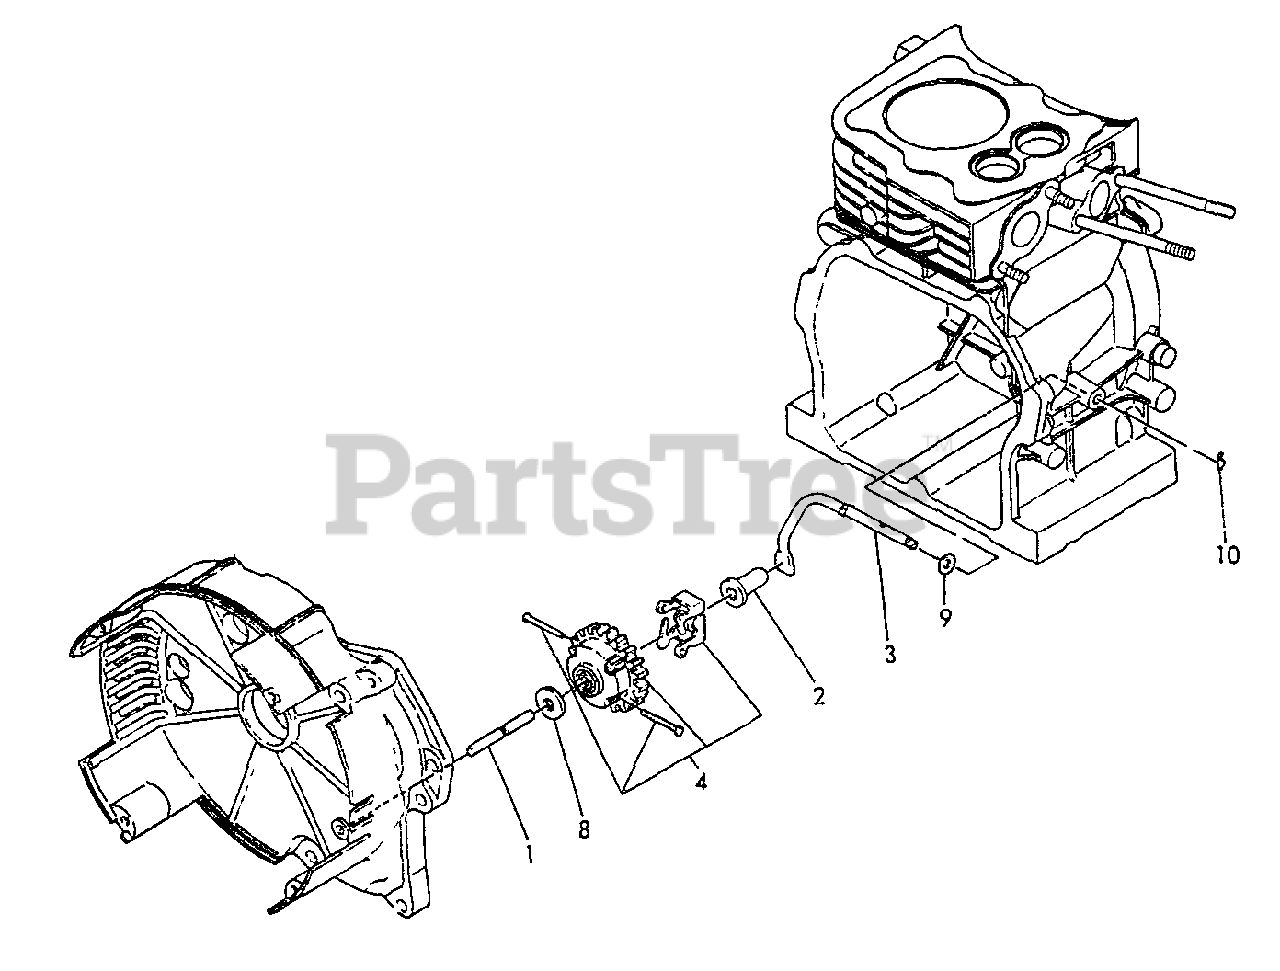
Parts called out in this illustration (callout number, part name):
1	SHAFT, GOVERNOR
2	SPINDLE, GOVERNOR
3	YOKE, GOVERNOR
4	GOVERNOR GEAR ASSY
8	WASHER - 6
9	WASHER - 6
10	PIN - 6 -- SNAP
